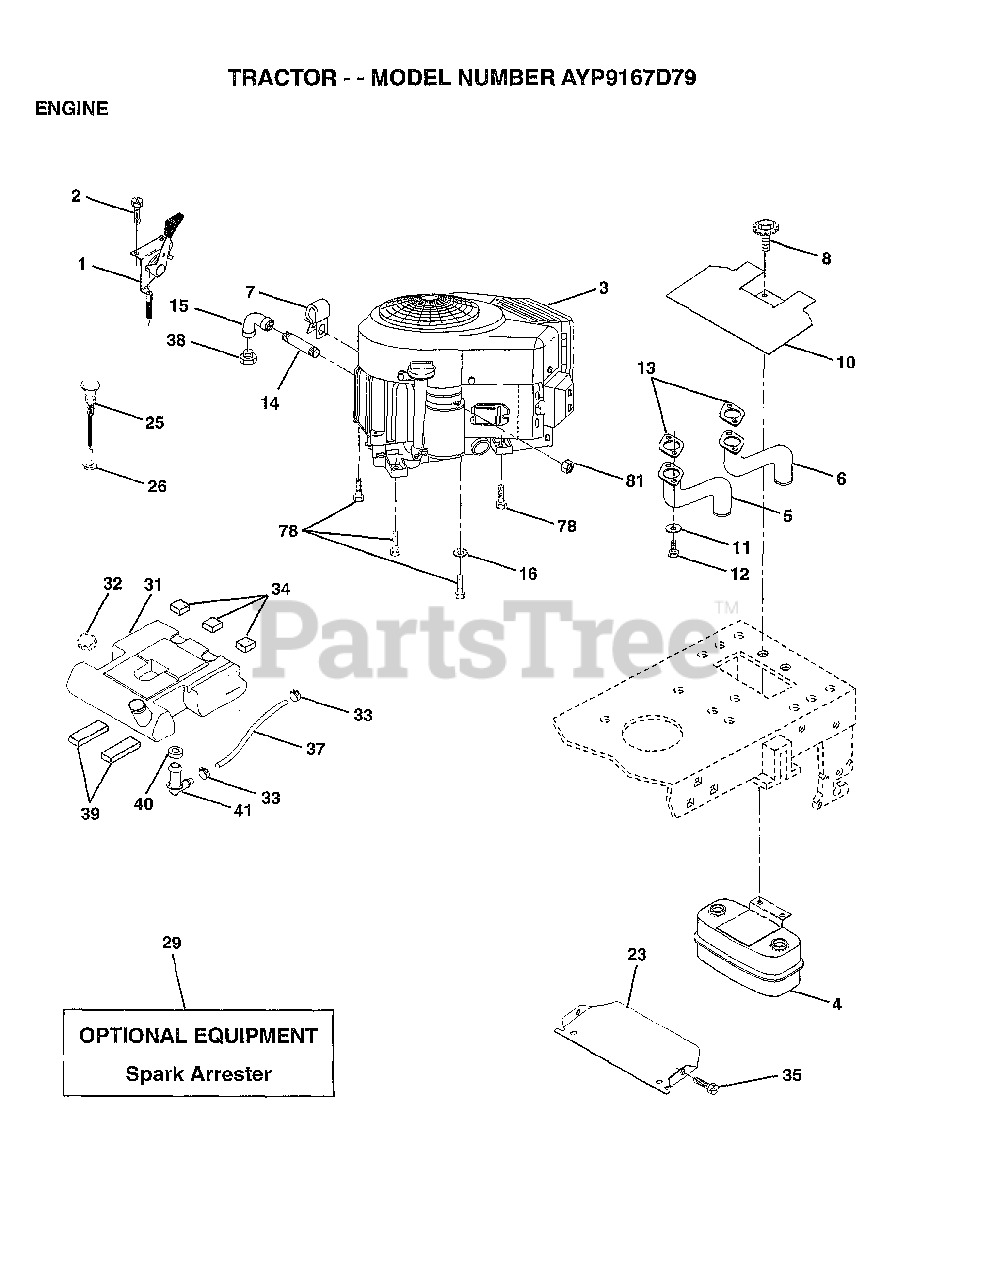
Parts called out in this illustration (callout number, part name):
1	CONTROL THROT. LH
2	SCREW LT
4	MUFFLER.TW.LOTONE
5	TUBE ASSY EXH LH
6	TUBE ASSY EXH RH
7	CLAMP.TUBE.DBL.EN
8	BOLT.5/16-18.UNC
10	SHIELD.HEAT.
14	PIPE NIPPLE LT
15	ELBOW
16	LOCKWASHER
23	SHIELD-HEAT
25	CONTROL.CHOKE.37
26	"NUT,KEPS 3/8-24IM"
31	TANK FUEL REAR
32	CAP ASM FUEL
33	HOSE CLAMP
34	PAD-SPACER LT
35	SCREW
37	FUEL LINE T
39	PAD IDLER TI
40	BUSHING OUTLET T
41	STEM.TANK.FUEL
78	SCREW
81	NUT
